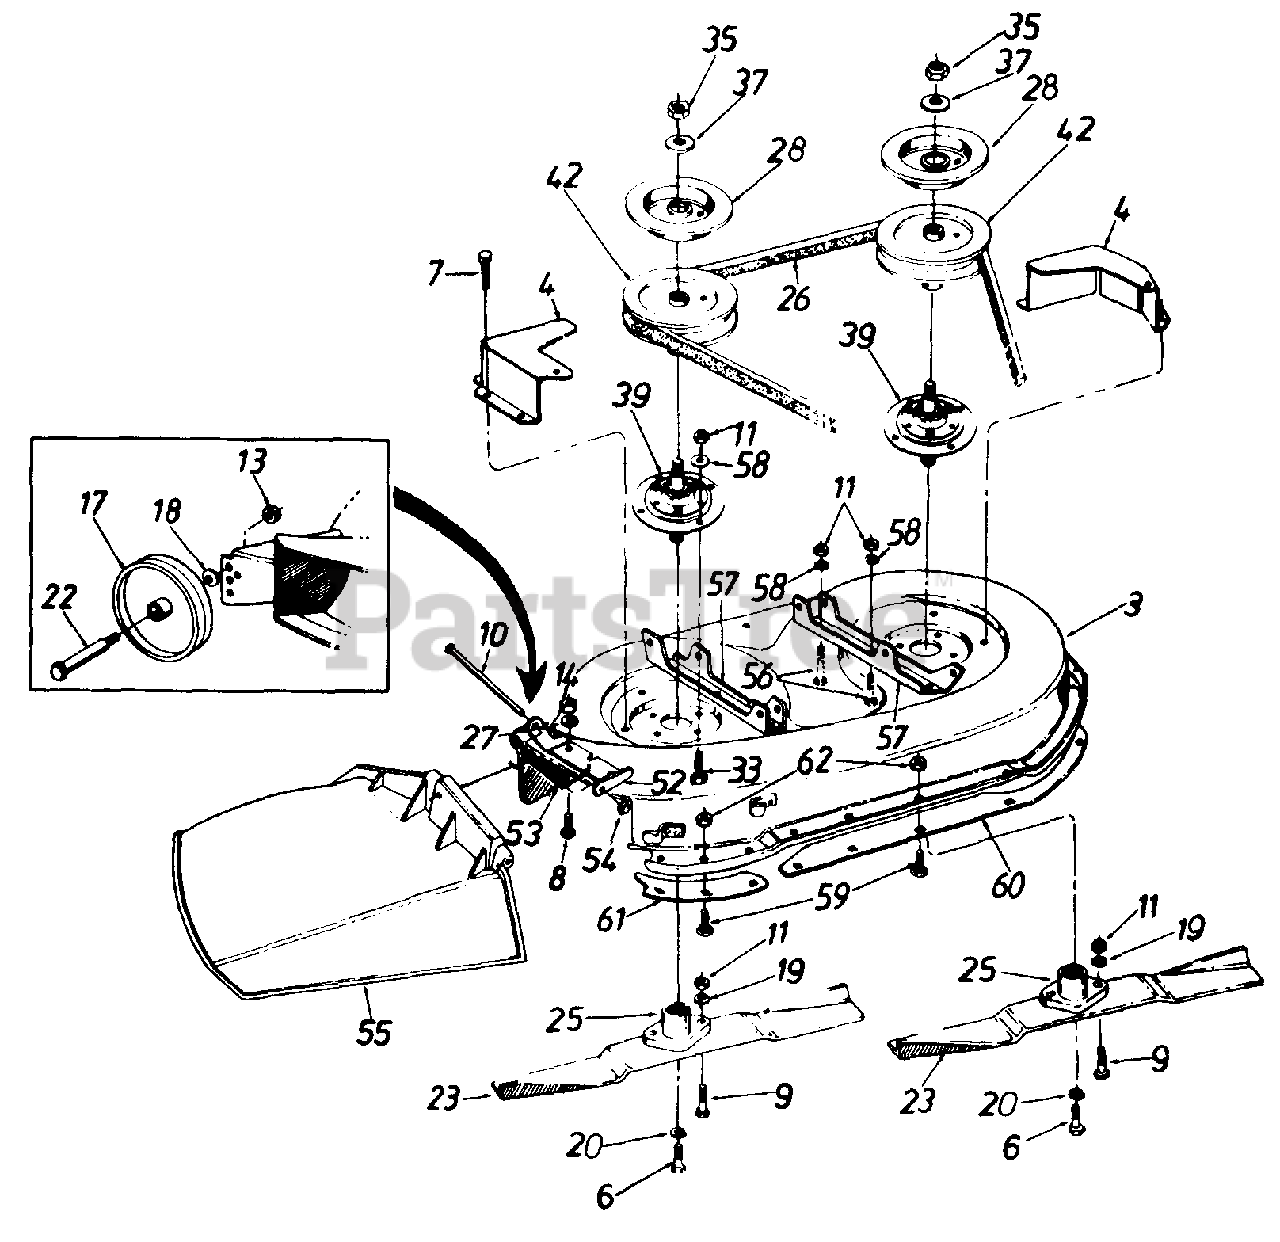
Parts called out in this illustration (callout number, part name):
6	Hex Bolt 3/8-24 x 1.0" Lg.
7	Hex Wash. Hd. TT-Tap Scr. 1/4-20 x .5" Lg.
8	Hex Bolt 1/4-20 x .62"
9	Hex Bolt Special 5/16-24 x 1.0"
10	Hinge Pin
11	Hex Nut 5/16-24 Thd.
13	Hex Top L-Nut 3/8-16 Thd.
14	Hex Nut 1/4-20 Thd.
17	Deck Wheel - 5"
18	Bell-Wash. .40" I.D. x .88" O.D.
19	L-Wash. 5/16" I.D.
20	L-Wash. 3/8" I.D. - H.D.
22	Shld. Bolt .498" Dia. x 1.53"
23	High-Lift Blade
25	Blade Adapter
26	V-Belt
27	Bell-Wash. 1/4" I.D.
28	Brake Disc
33	Hex Bolt 5/16-24 x .75" Lg.
35	Hex Jam Nut 5/8-18 Thd.
37	L-Wash. 5/8" I.D.
39	Blade Spindle Ass'y. Comp.
42	5.5" Dia. Pulley
52	Hinge Mtg. Brkt.
53	Torsion Spring
55	Chute Ass'y. Comp.
56	Hex Bolt 5/16-24 x .75" Lg.
59	Carr. Bolt 1/4-20 x .5" Lg.
62	Hex Sems Nut 1/4-20 Thd.
